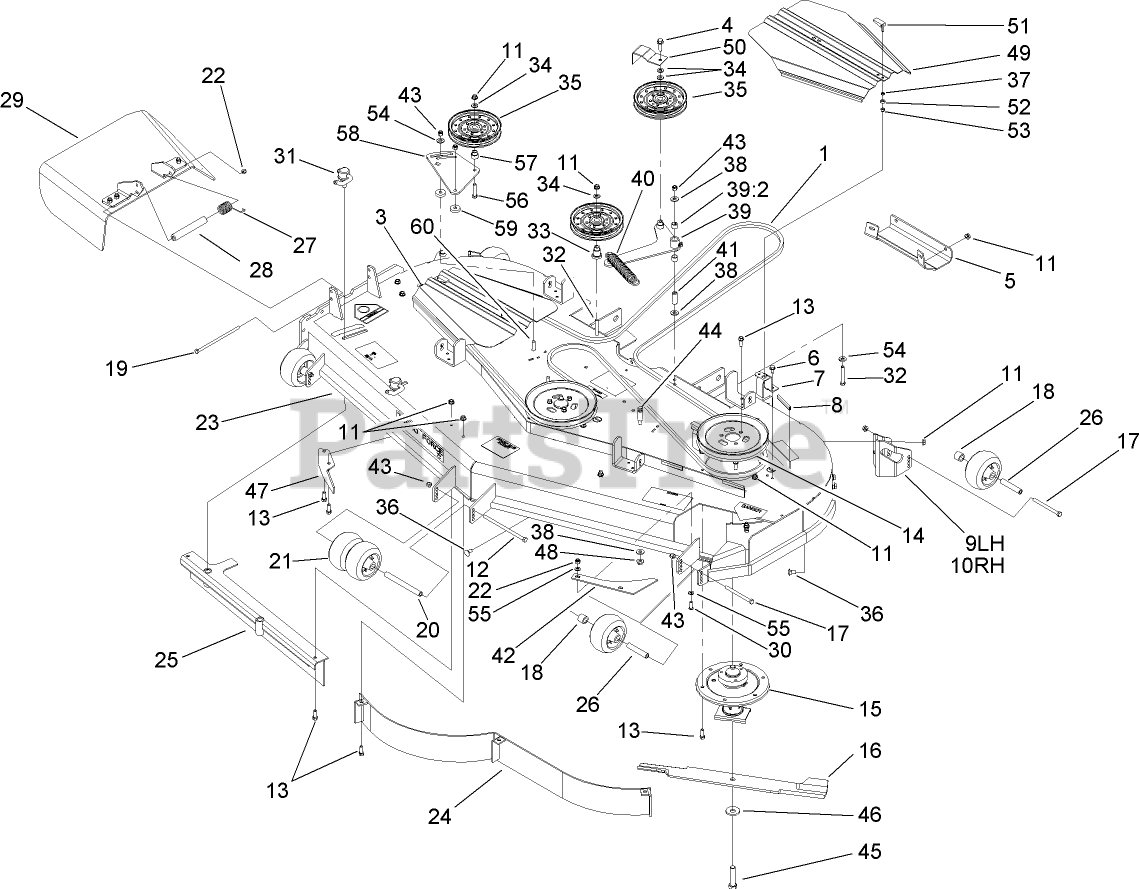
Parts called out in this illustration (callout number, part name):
3	COVER-BELT
4	SCREW-HHF
5	Plate-Skid
6	SCREW-HWHTF
7	BRACKET-COVER
8	STRIP-SEAL
9	MOUNT-WHEEL, LH
10	MOUNT-WHEEL, RH
11	NUT-HHF, WHIZ
12	SCREW-HH
13	SCREW-HWH
14	Pulley
15	SPINDLE ASM
16	BLADE-HI FLOW, 24.5 INCH
17	SCREW-HH
18	TUBE-SPACER
19	SCREW-HH
20	SPACER-WHEEL
21	ROLLER-SCALP, ANTI
22	NUT-LOCK, NI
23	DECK DECAL ASM
26	TUBE-SPANNER
27	SPRING-TORSION
28	SPACER
29	RUBBER DEFLECTOR ASM
30	SCREW-HSBH
31	LEVER ASM
32	SCREW-HH
33	MOUNT-PULLEY
34	WASHER-FLAT
35	Idler-Flat
36	SCREW-CARR
37	WASHER
38	WASHER-FLAT
39	DECK IDLER ARM ASM
39:2	SLEEVE-BEARING
40	SPRING-EXTENSION
41	BUSHING
42	PLATE-TURBO
43	NUT-LOCK, NI
44	PIN-THREADED, SPRING ANCHOR
45	Screw-Cap
46	Washer-Blade Bolt, Heavy
47	BAFFLE-DISCHARGE
48	NUT-HF
49	COVER-BELT
50	GUIDE-BELT
51	HANDLE-LATCH, SWELL
52	BUSHING-LATCH, SWELL
53	NUT-LOCK, HH
54	WASHER-BELLEVILLE
55	WASHER-SPRING
56	SCREW-HH
57	BUSHING-IDLER
58	Plate-Idler
59	Spacer
60	SCREW-CARR
